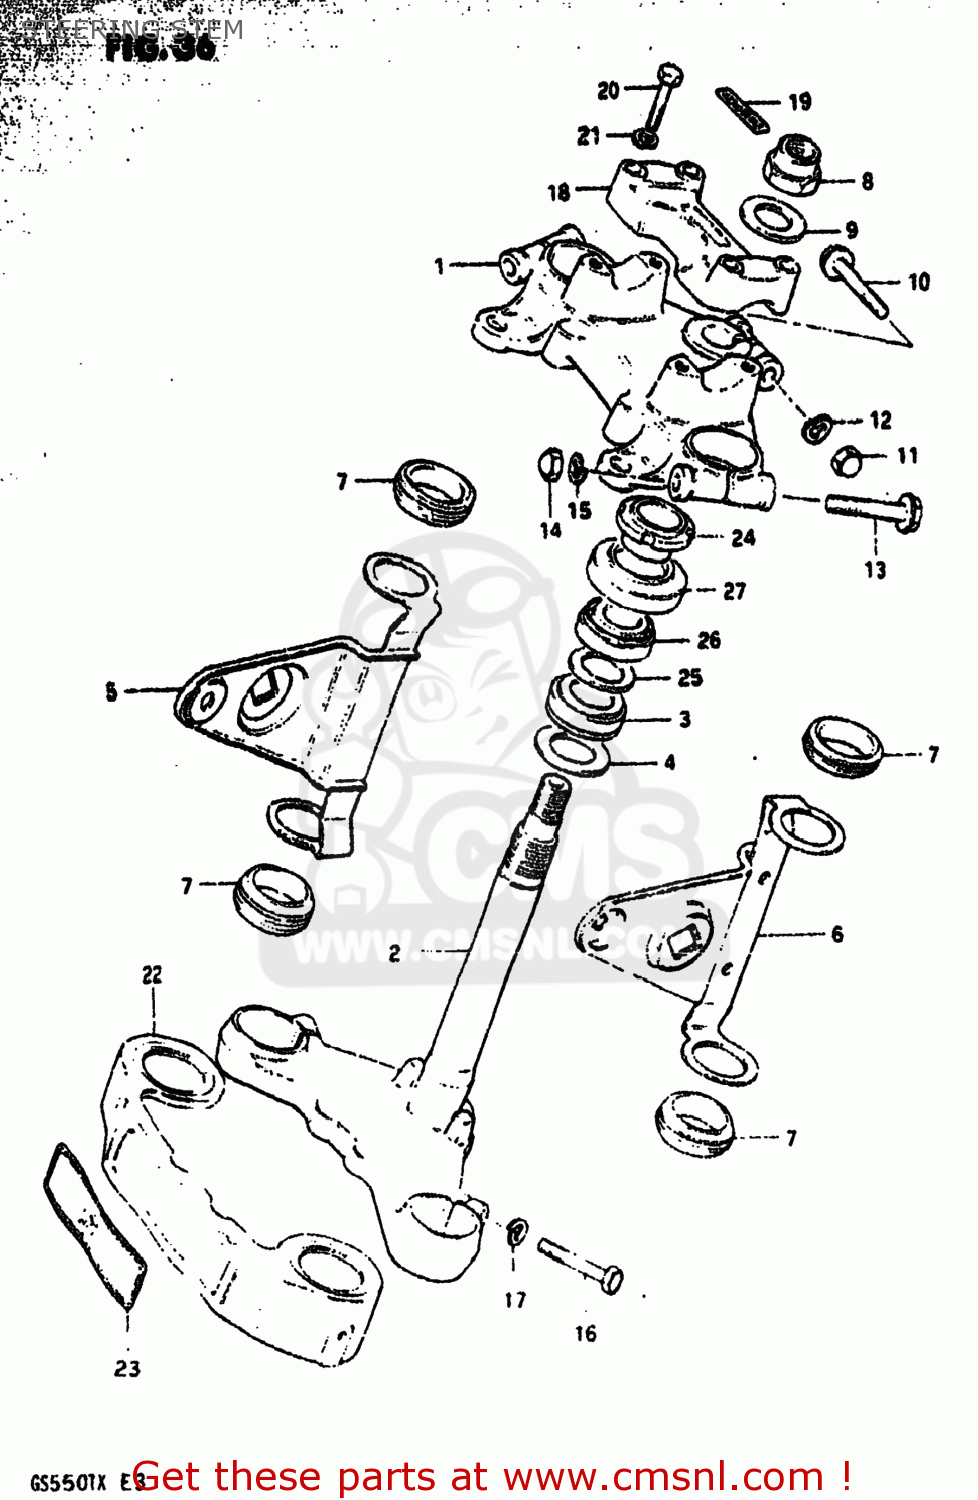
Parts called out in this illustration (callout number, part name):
1	HEAD,STEERING STEM
2	STEM,STEERING
3	BEARING
4	WASHER,THRUST
5	BRACKET,HEADLAMP,RIGHT
6	BRACKET,HEADLAMP,LEFT
7	CUSHION,HEADLAMP BRACKET
8	NUT,FR FORK UPR BRACKET
9	WASHER
10	BOLT
11	NUT,M8X1.25X12
12	LOCK WASHER
13	BOLT 10X55
14	NUT
15	LOCK WASHER
16	BOLT 10X40
17	LOCK WASHER
18	HOLDER,HANDLEBAR
19	EMBLEM,HANDLE CLAMP
20	BOLT
21	LOCK WASHER
22	COVER,FRONT FORK
23	EMBLEM
24	NUT,STEERING STEM
25	WASHER(18.5X24X1)
26	TAPER,ROLLER BEARING
27	DUST SEAL,STEERING,UPPER
